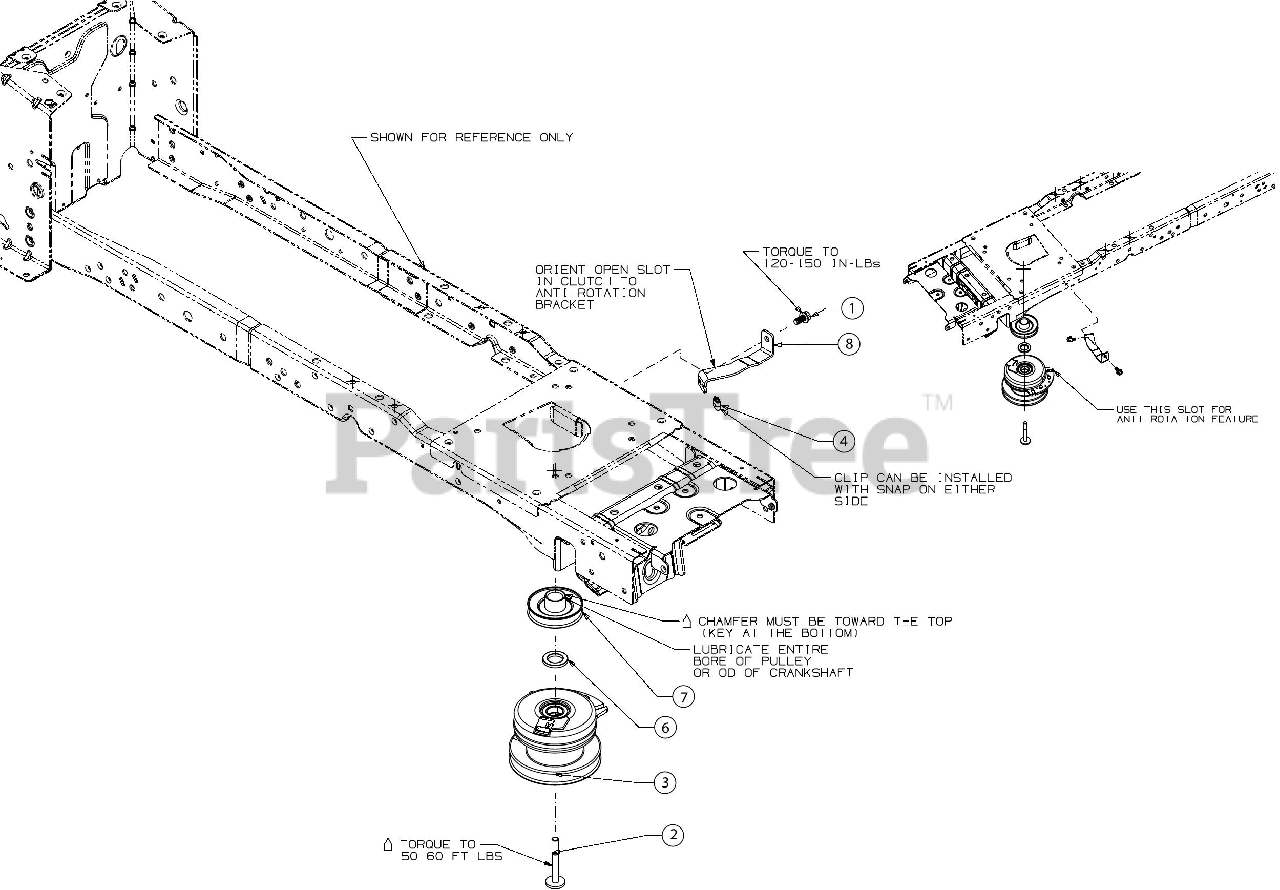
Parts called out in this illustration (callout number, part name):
1	SCREW 3/8-16 x 3/4
2	SCREW 7/16-20 x 3.50
3	ELECTRIC PTO CLUTCH
4	CLUTCH BRACKET GROMMET
7	ENGINE PULLEY
